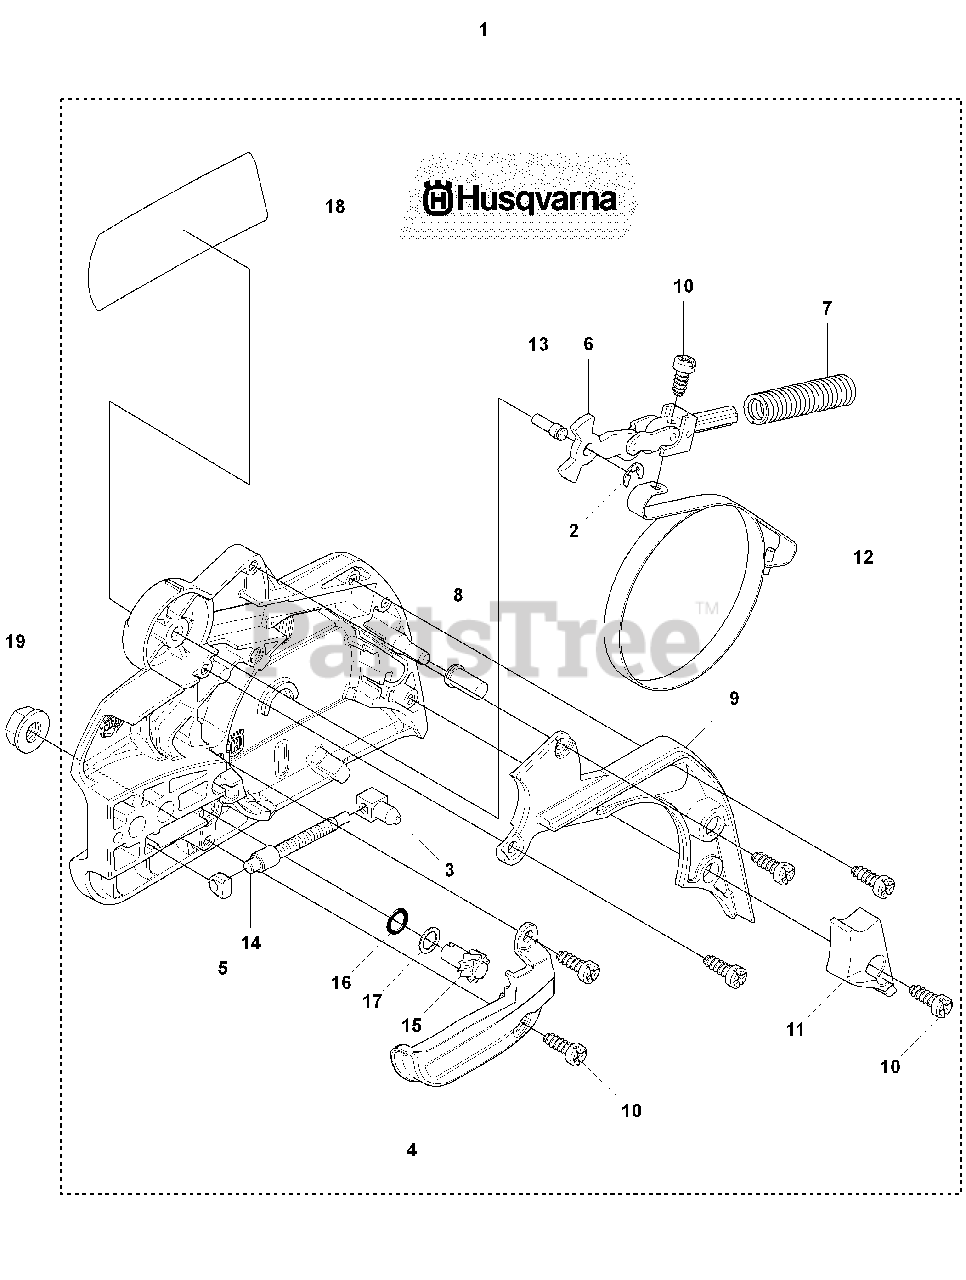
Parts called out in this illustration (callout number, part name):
1	CLUTCH COVER
4	CHAIN GUIDE
9	COVER, CHAIN BRAKE
11	WEAR GUARD, CHAIN
12	BRAKE BAND
15	WORM WHEEL
18	LABEL 400 SERIES
19	NUT M8 FLANGE
